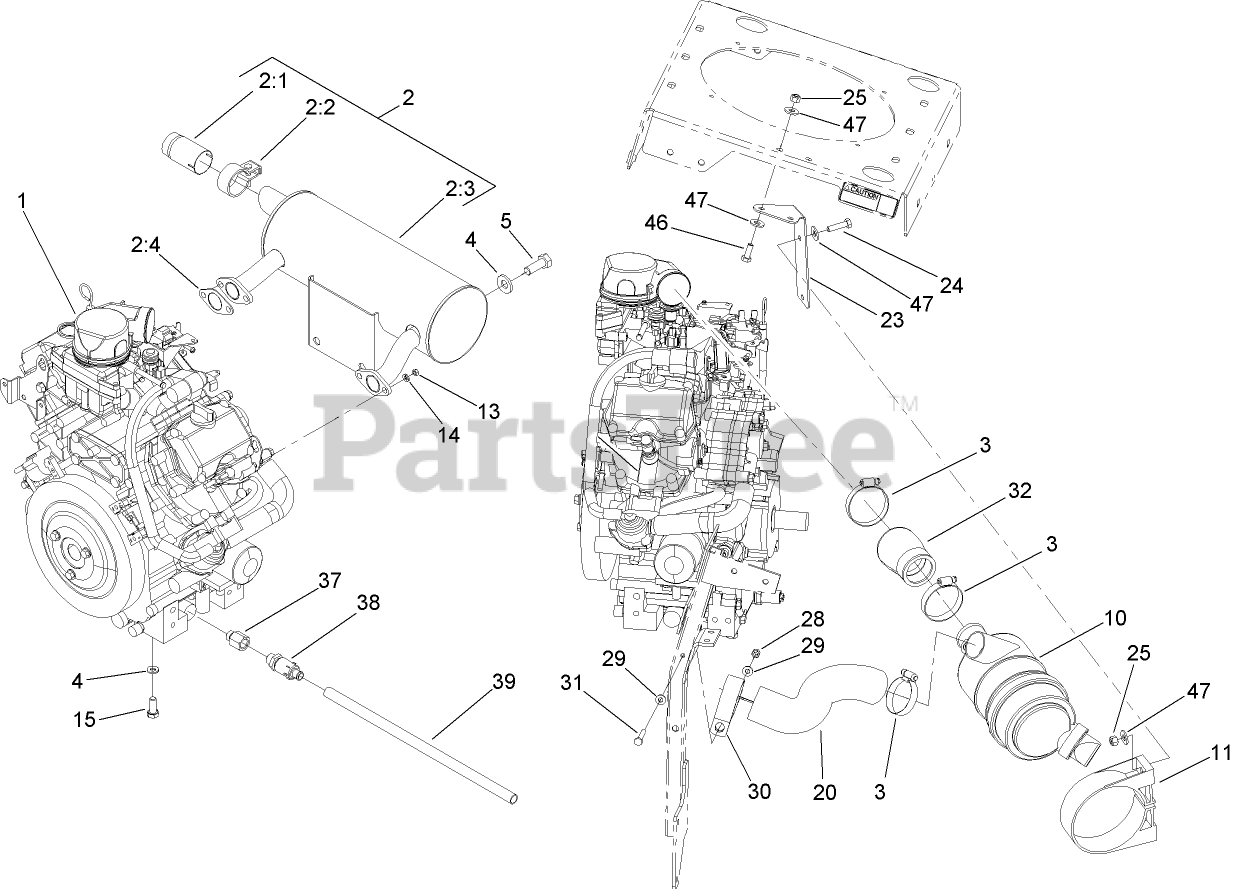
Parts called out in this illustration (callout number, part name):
2	MUFFLER KIT (W/ ARRESTER)
2:1	ARRESTOR-SPARK
2:2	CLAMP-MUFFLER
2:3	MUFFLER
2:4	GASKET-EXHAUST
3	CLAMP-HOSE
4	WASHER-BELLEVILLE
5	SCREW-HH
10	AIR CLEANER ASM
11	BRACKET-MOUNTING
13	NUT-HEX
14	WASHER-LOCK
15	SCREW-HH
20	HOSE-AIR CLEANER, INLET
23	BRACKET-MOUNT, AC
24	SCREW-HH
25	NUT-LOCK, NI
28	NUT-LOCK, NI
29	WASHER-FLAT
30	CLAMP-R
31	SCREW-HH
32	HOSE-AIR CLEANER, OUTLET
37	ADAPTER
38	VALVE-DRAIN, OIL
39	TUBE-DRAIN, OIL
46	SCREW-HH
47	WASHER-FLAT
